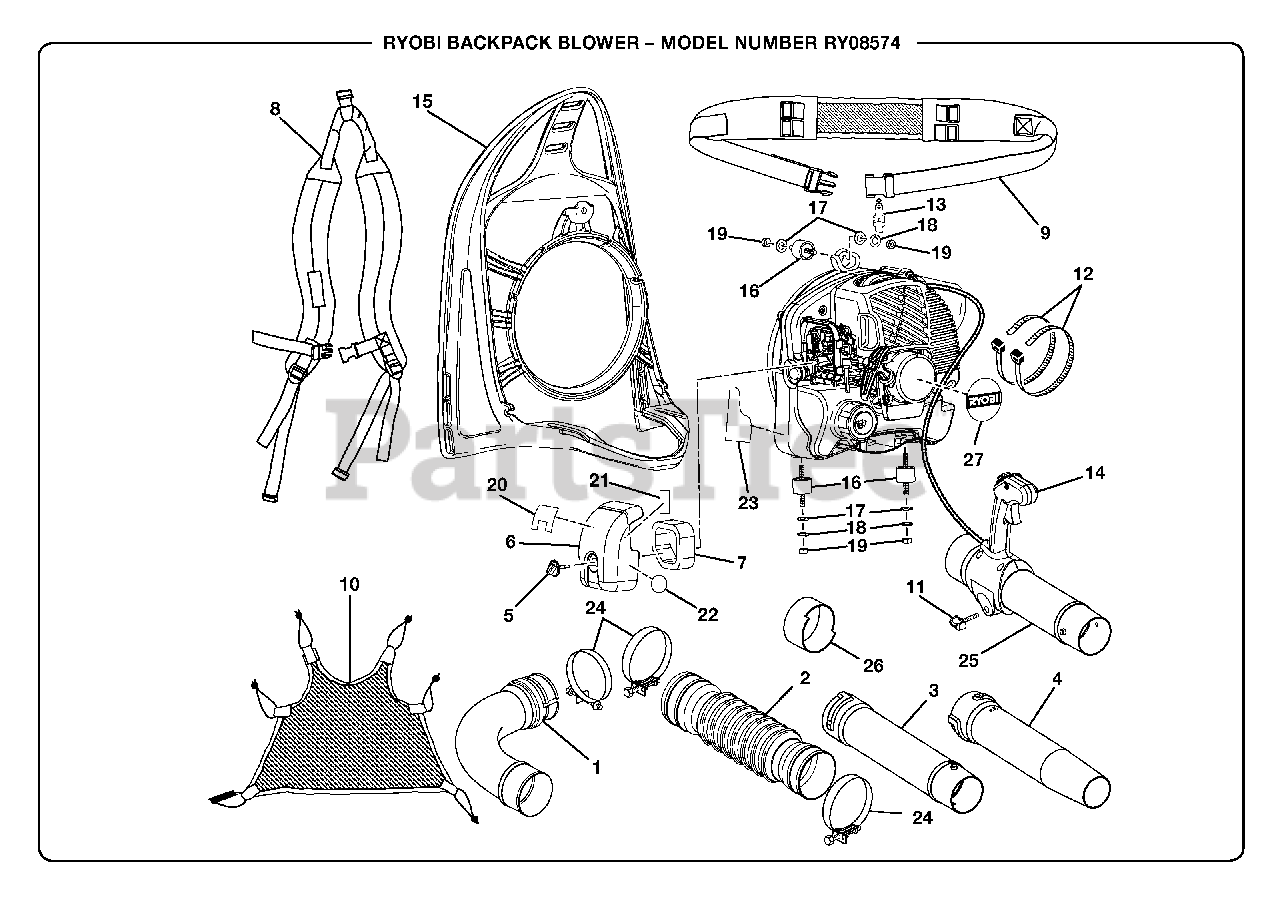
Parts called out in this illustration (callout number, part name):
1	Elbow Tube
3	Straight Tube (Upper Tube)
4	Nozzle (Lower Tube)
5	Air Filter Knob
6	Air Filter Cover
7	Air Filter
8	Shoulder Harness Assembly
9	Waist Harness
10	Mesh Backing
11	Blower Knob (1.35 in [34.3 mm])
12	Cable Tie
13	Spark Plug (Champion RCJ6Y)
14	Control Assembly
15	Backpack Frame
16	Vibration Isolators
17	Flat Washer
18	Spring Washer
19	Hex Nut (1/4 - 20)
20	Starting Instructions Label
21	Starting Label
22	Zip Start Label
23	Warning Label
24	Tube Clamp
25	Tube-Handle
27	Label, Starter Pack
